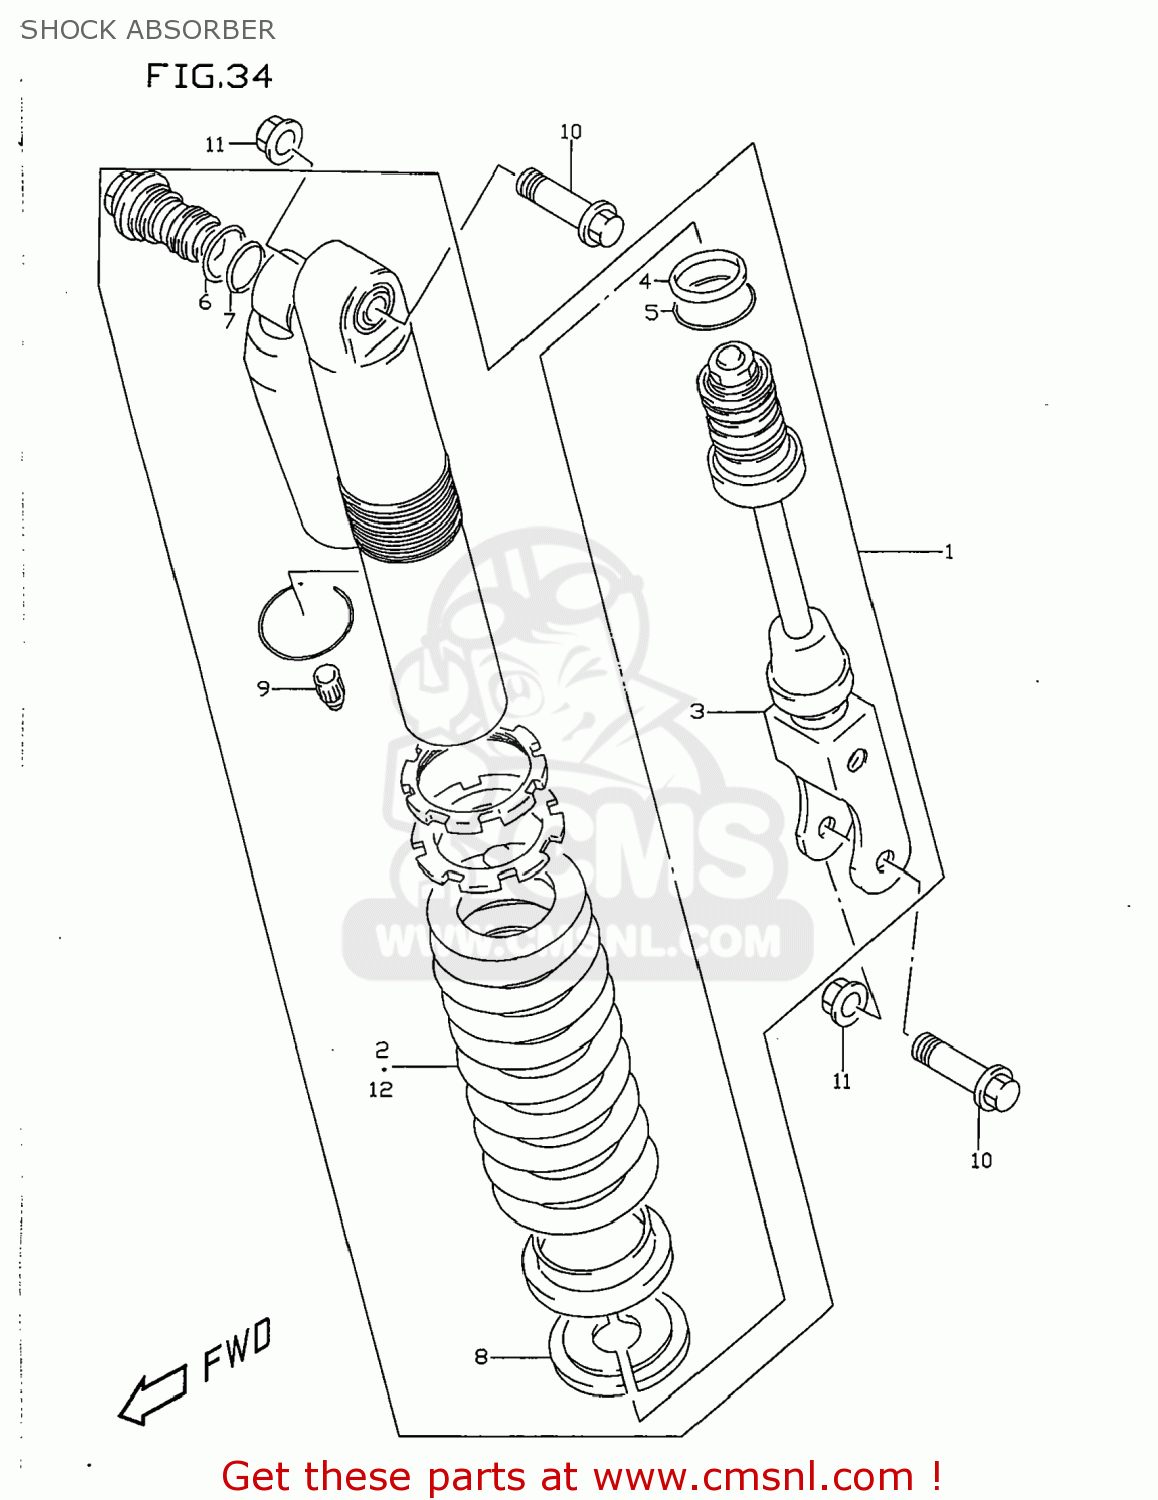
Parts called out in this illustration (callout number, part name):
1	ABSORBER ASSY,RR SHOCK
2	SPRING
3	ROD,PISTON
4	O RING
5	RING,PISTON ROD STOPPER
6	O RING
7	O-RING,FORK BOLT,LOWER
8	SEAT,SPRING STOPPER
9	CAP
10	BOLT,RR CUSHION ROD UPR
11	NUT
12	SPRING(SOFT)
